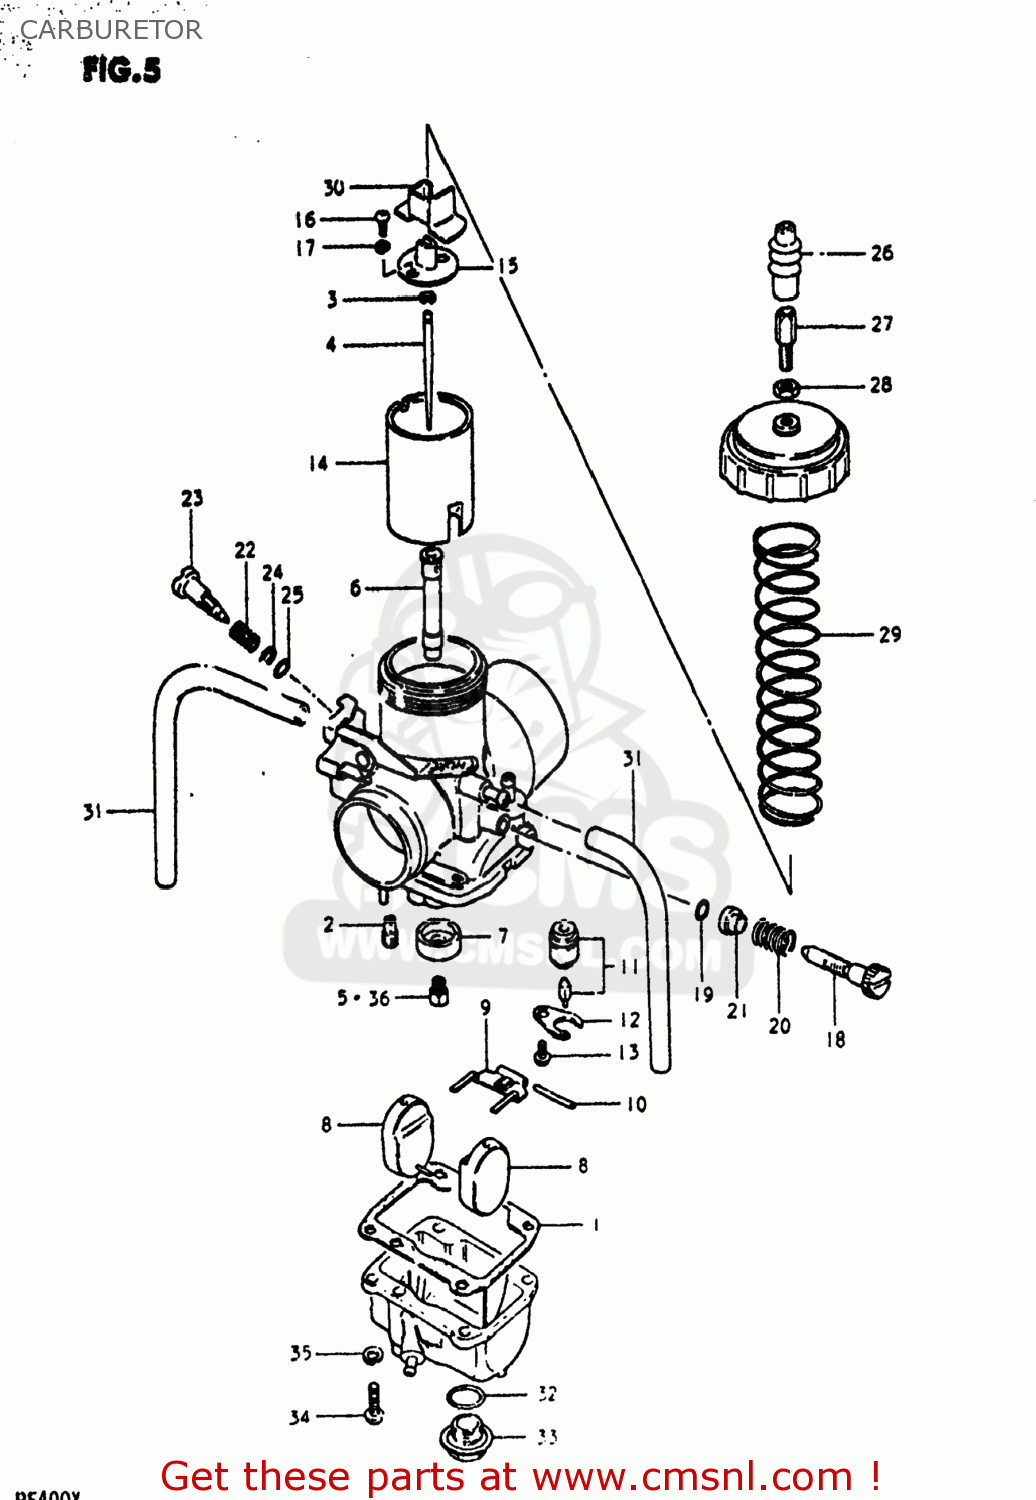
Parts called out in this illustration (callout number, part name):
1	GASKET,FLOAT CAHMBER (NAS)
2	JET,PILOT
3	CLIP
4	NEEDLE JET
5	JET
6	JET,NEEDLE
7	RING,MAIN JET FIXING
8	FLOAT
9	ARM,FLOAT
10	PIN,FLOAT
11	VALVE ASSEMBLY,NEEDLE
12	PLATE
13	SCREW
14	VALVE,THROTTLE
15	CONNECTOR
16	SCREW
17	LOCK WASHER
18	SCREW,THROTTLE STOP
19	O-RING
20	SPRING,THROTTLE STOP
21	COVER
22	SPRING
23	SCREW,PILOT AIR
24	WASHER,PILOT AIR SCREW
25	O RING
26	CAP,CABLE ADJUSTER
27	ADJUSTER,CABLE
28	NUT
29	SPRING,THROTTLE VALVE RETURN
30	COVER,HOLDER
31	HOSE
32	O-RING
33	PLUG
34	SCREW
35	LOCK WASHER
36	JET
